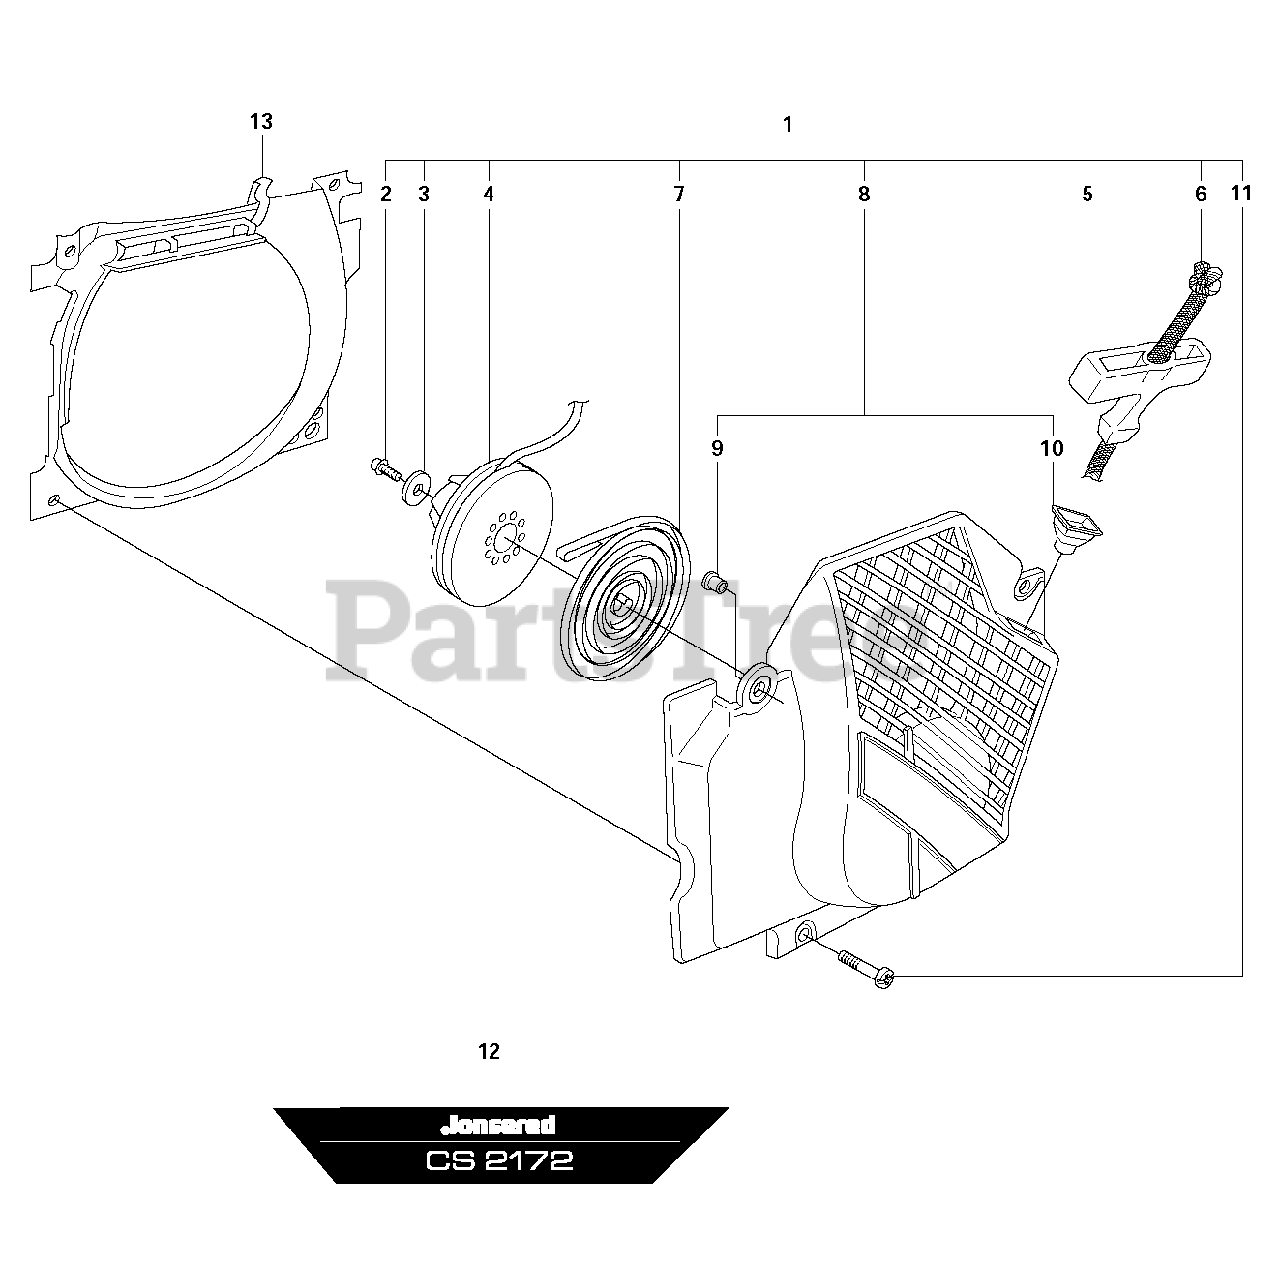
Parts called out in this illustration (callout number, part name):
1	STARTER ASSY
2	SCREW
3	WASHER
4	STARTER PULLEY
5	STARTER HANDLE
6	STARTER ROPE
7	SPRING
8	STARTER HOUSING
10	SLEEVE
11	SCREW
12	LABEL
13	AIR CONDUCTOR
